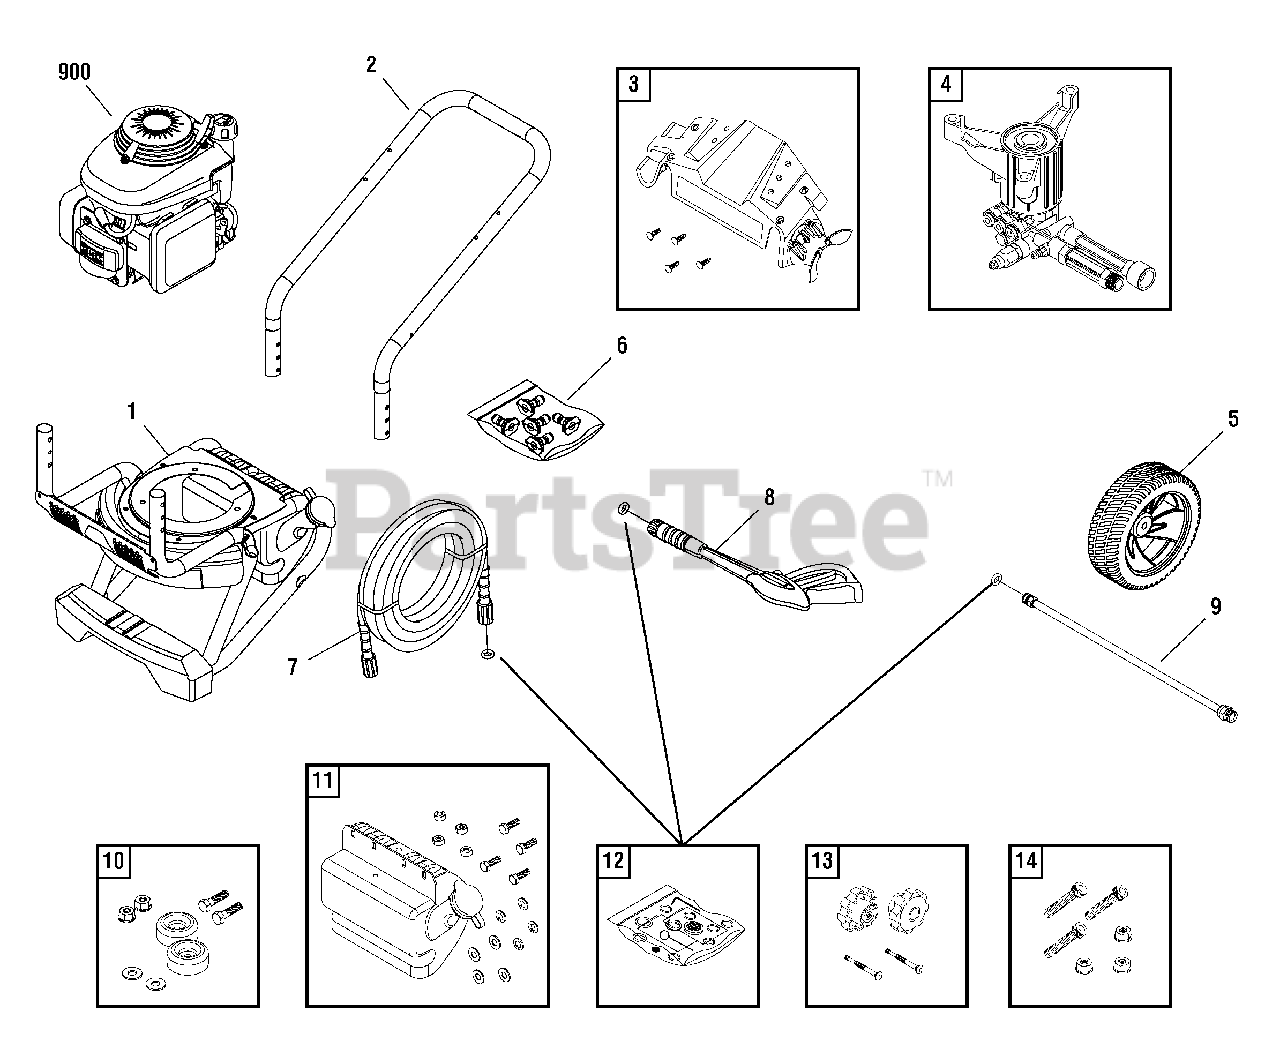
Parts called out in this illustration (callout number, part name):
6	KIT, QC Nozzles
7	HOSE
8	GUN
9	EXTENSION, QC
10	MOUNT, Vibration
13	KIT, Hardware, Handle
14	KIT, Hardware, Pump Mounting
900	* ENGINE
